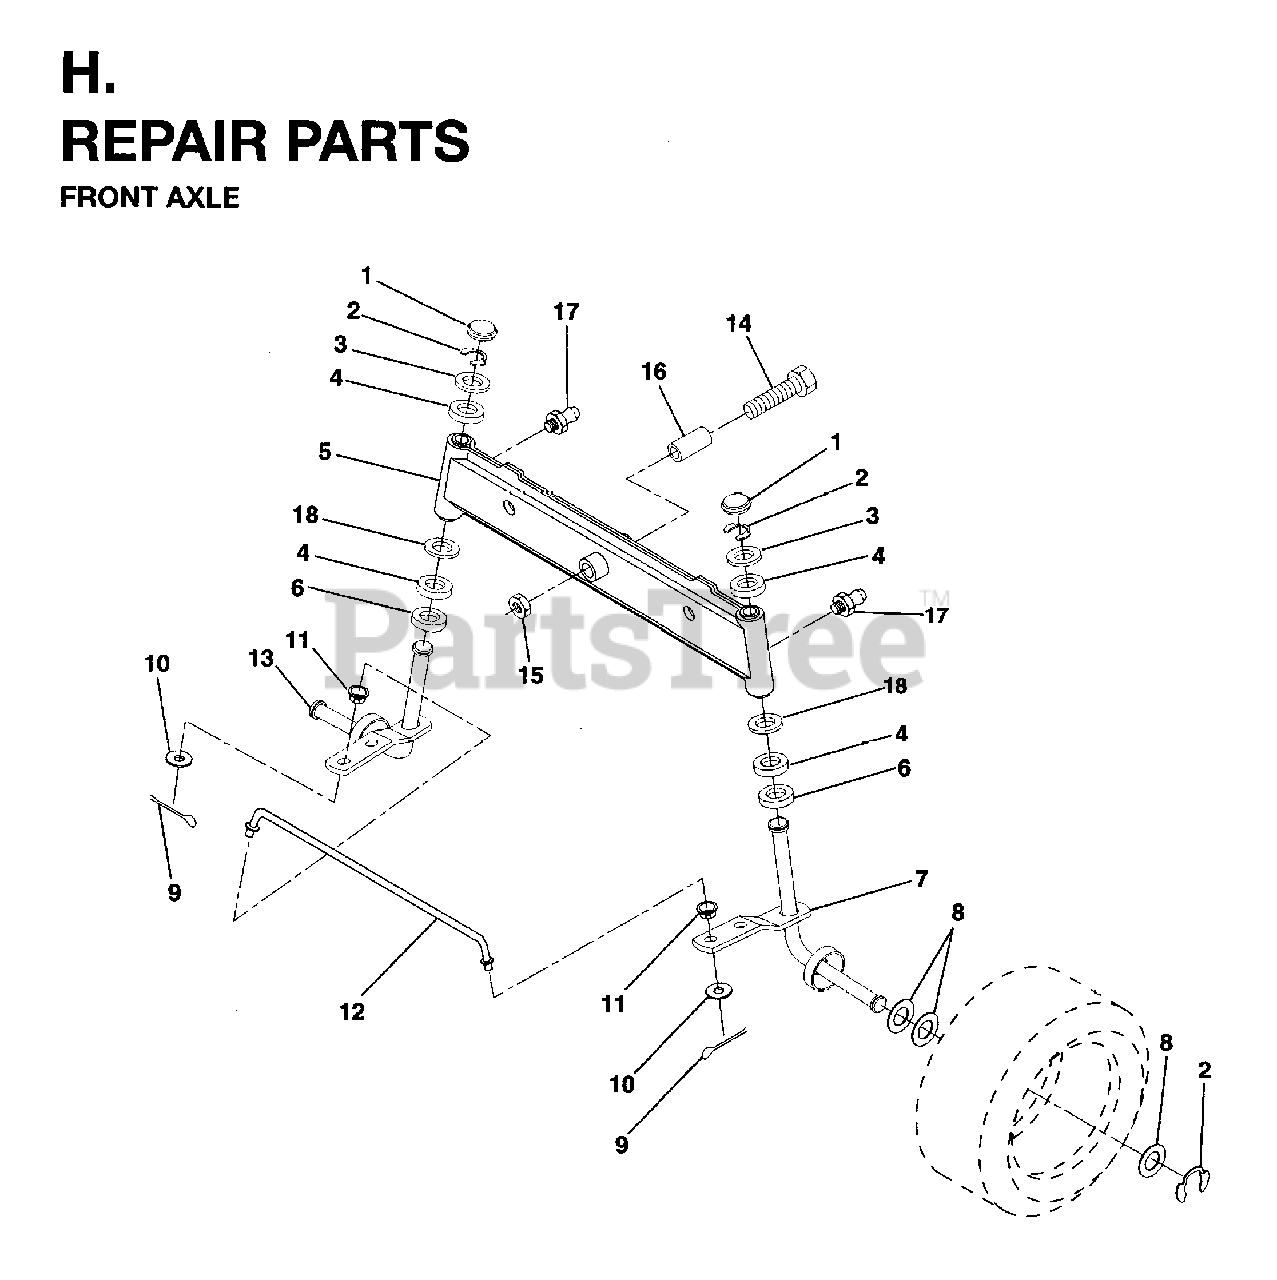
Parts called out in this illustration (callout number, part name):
1	CAP.SPINDLE
2	RING CLIP
4	BEARING.STEERING.COLUMN
5	AXLE ASSY
6	WASHER THRUST
7	SPINDLE ASSY RH NLA
9	COTTER PIN
10	WASHER
11	BUSHING.DRAGLINK
12	TIE ROD
13	SPINDLE ASSY LH
14	BOLT.HEX.5/8-11
15	LOCKNUT
16	BEARING
17	ZERK M
